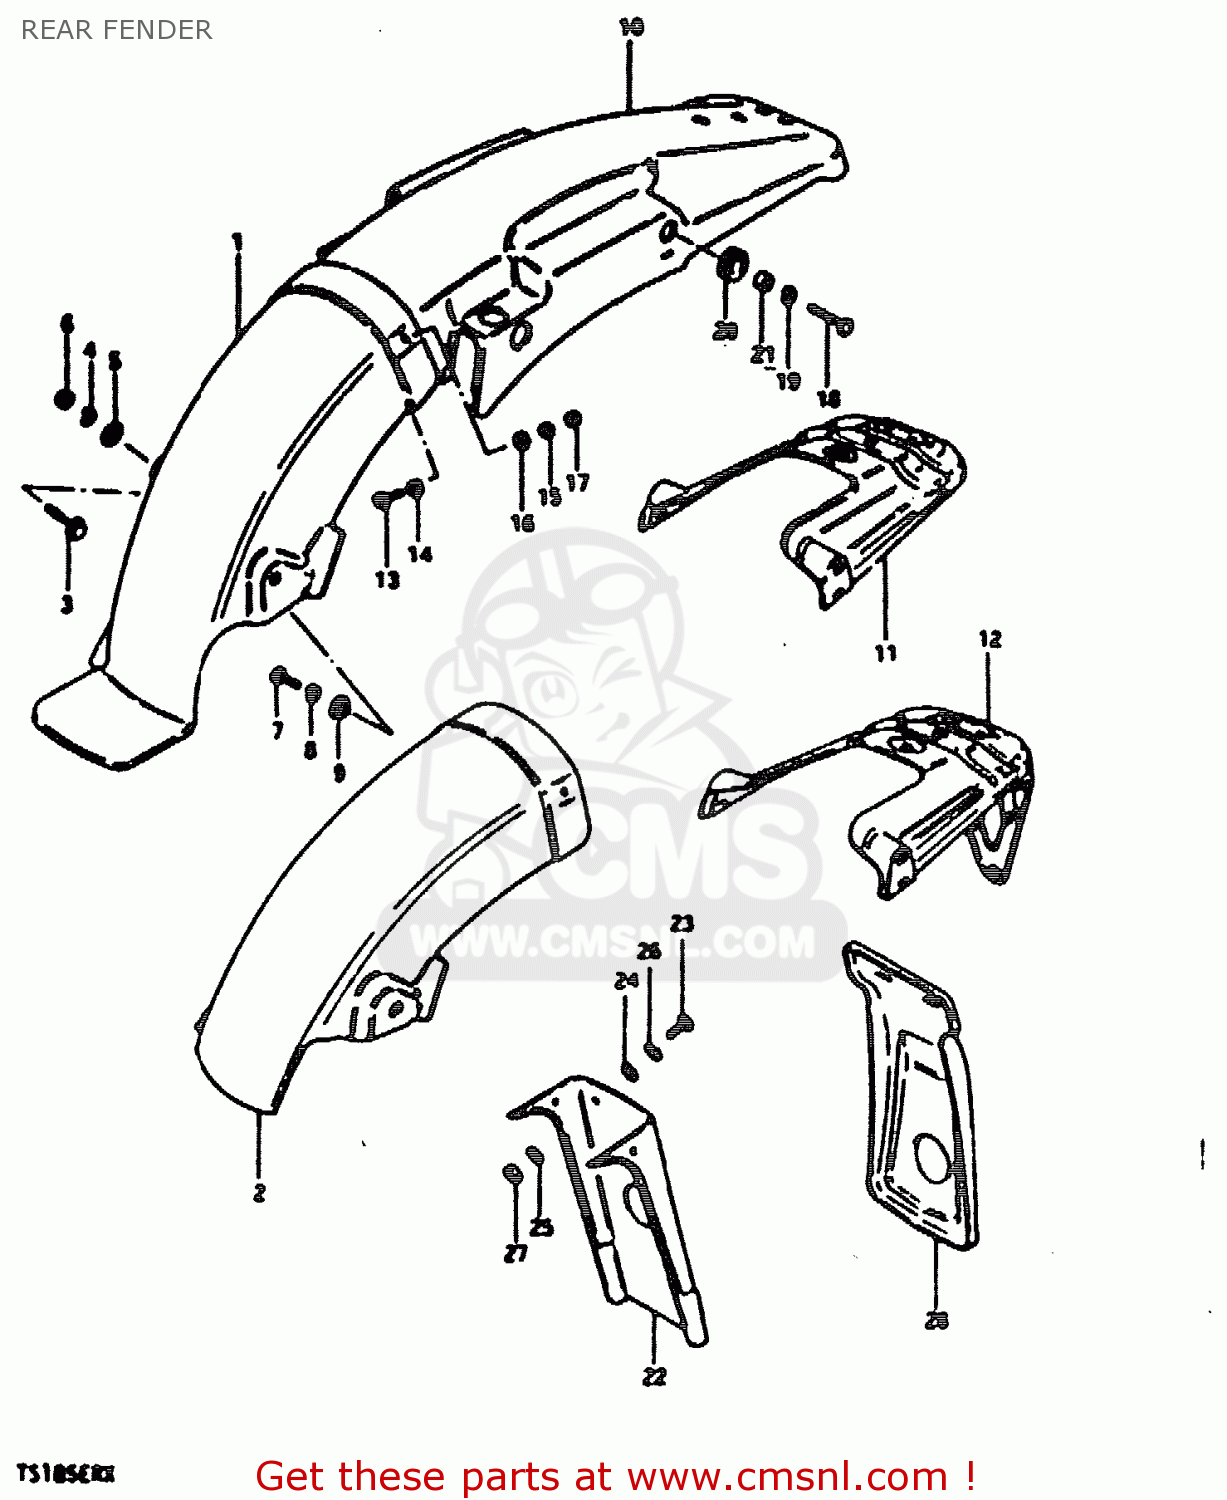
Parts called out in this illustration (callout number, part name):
1	FENDER,REAR
3	BOLT
4	LOCK WASHER
5	WASHER
6	NUT
7	BOLT
8	LOCK WASHER
9	WASHER
10	FENDER, REAR
11	REINFORCEMENT,RR FENDER
13	BOLT
14	WASHER (5.5X16X1.2)
15	LOCK WASHER
16	WASHER(5.2X16X1)
17	NUT
18	BOLT (8X30)
19	LOCK WASHER
20	CUSHION
21	SPACER (8.2X12X7.5)
28	MUD GUARD,REAR FENDER
